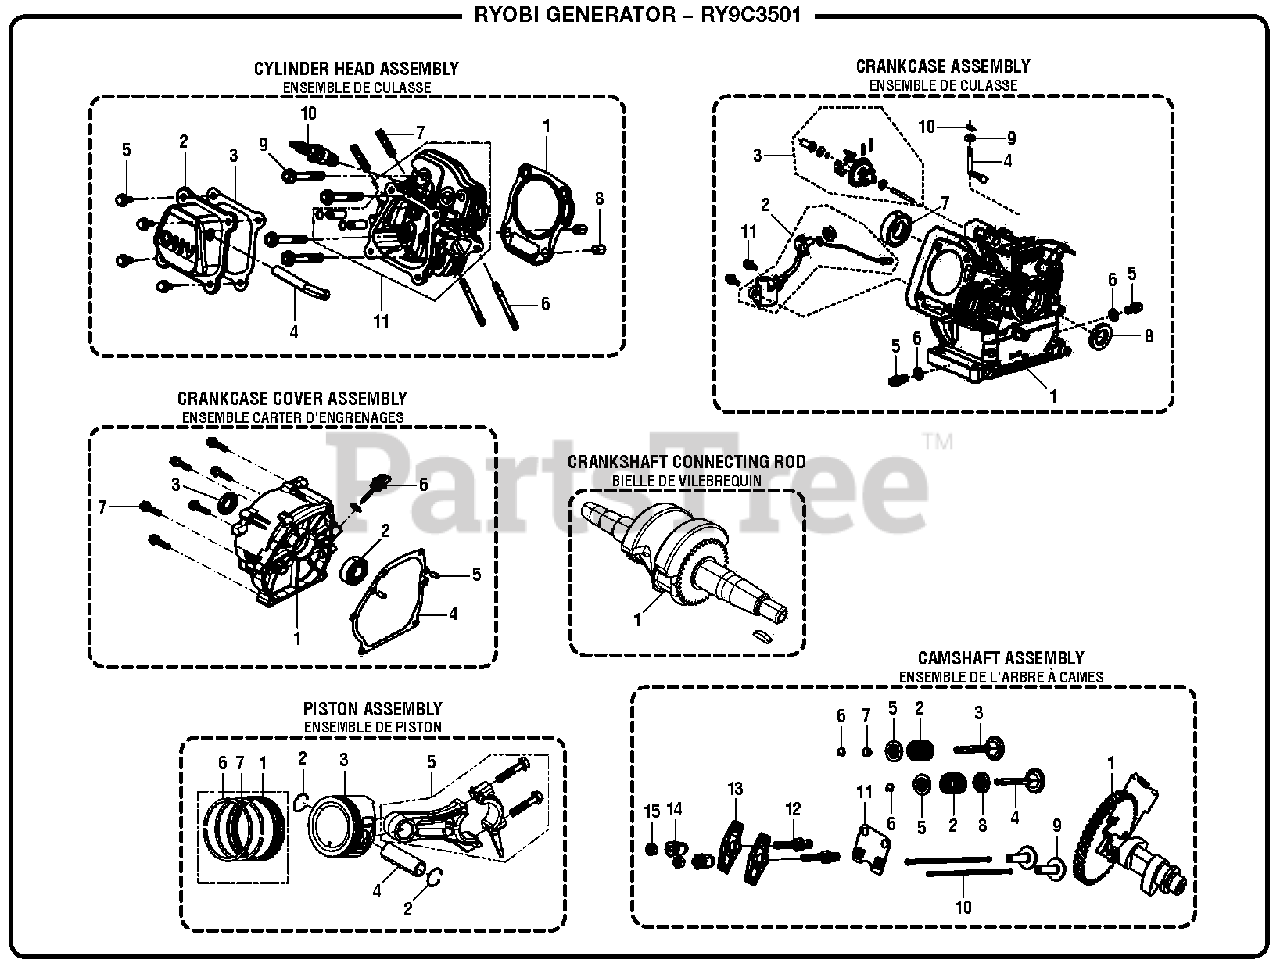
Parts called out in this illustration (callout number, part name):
1	Cylinder Head Gasket
1	Crankcase Assembly
1	Crankcase Cover
1	Crankshaft Assembly
1	Oil Ring Kit
1	Camshaft Assembly
2	Cylinder Head Cover Assembly
2	Engine Oil Sensor
2	Ball Bearing
2	Piston Pin Clip
2	Valve Spring
3	Cylinder Head Cover Gasket
3	Governor Gear Assembly
3	Oil Seal
3	Piston
3	Exhaust Valve
4	Breather Tube
4	Governor Arm
4	Crankcase Gasket
4	Piston Pin
4	Intake Valve
5	Drain Plug
5	Connecting Rod
5	Valve Spring Seat
6	Stud
6	Washer
6	Oil Dipstick Assembly
6	The First Ring
6	Valve Lock Clip
7	Stud
7	Ball Bearing
7	The Second Ring
7	Valve Rotator
8	Oil Seal
8	Seal Guide
9	Cylinder Head Bolt
9	Washer
9	Valve Tappet
10	Spark Plug
10	Pin
10	Valve Lifter
11	Cylinder Head Assembly
11	Lifter Stop Plate Assembly
12	Valve Adjusting Bolt
13	Valve Rocker
14	Valve Adjusting Nut
15	Valve Lock Nut
